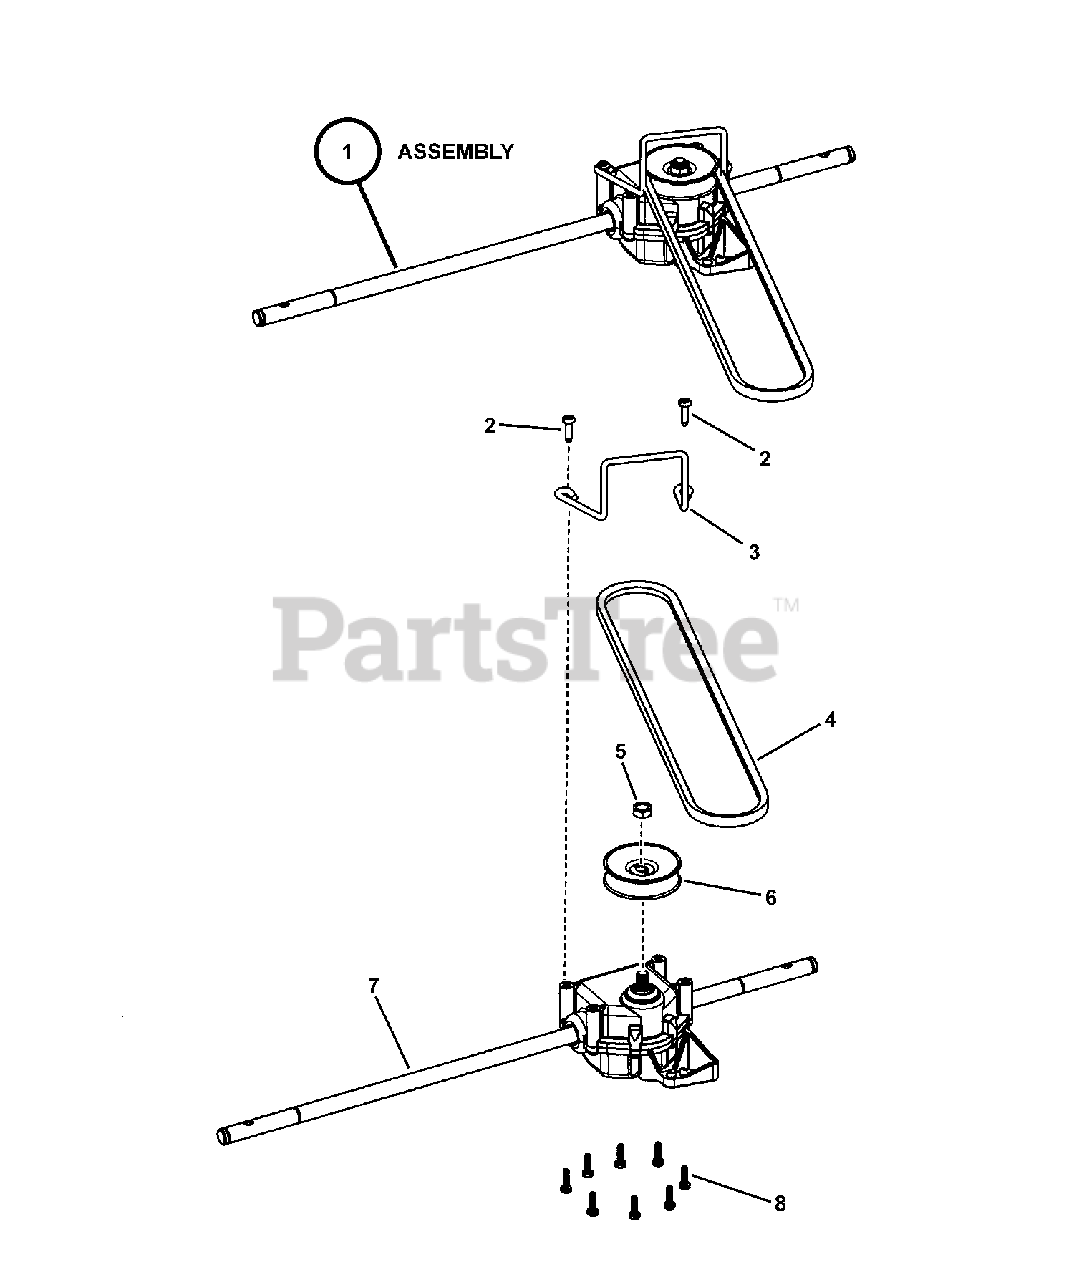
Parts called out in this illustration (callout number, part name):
1	ASSY, TRANSMISSION, 21 (not sold as an assembly)
2	SCREW, #10-16 x 3/4" Pan Head Self-Tap, Combo
3	BELT GUIDE, Transmission
4	BELT, Traction Drive, 21" Pivot Handle
5	NUT, 3/8-16 Hex Center Lock Jam, Black
6	PULLEY, Trans Var Speed, LC WBM
7	TRANSMISSION, 21" WBM, RD, Snapper
8	SCREW, 7mm x 1 x .550 AB Point
